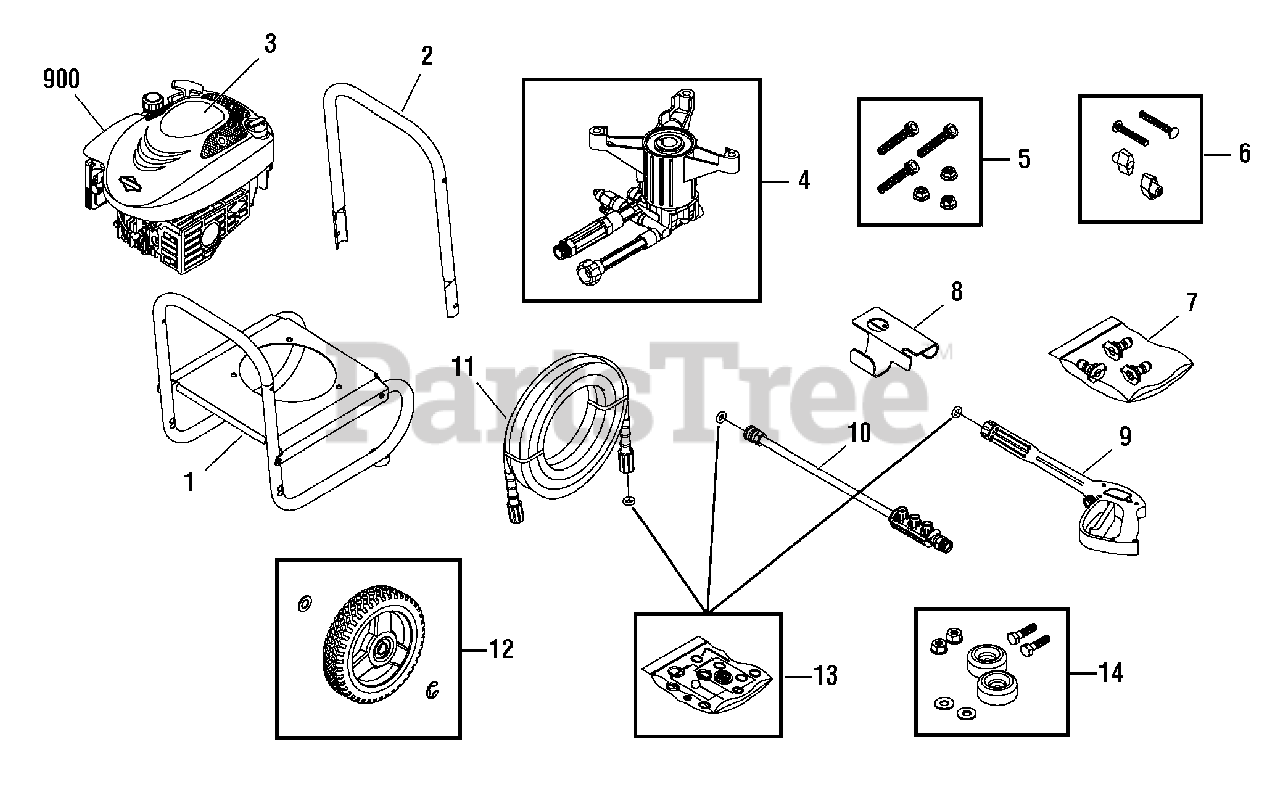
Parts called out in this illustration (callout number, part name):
2	HANDLE
4	PUMP
5	KIT, Hardware, Pump Mounting
6	KIT, Hardware, Handle
7	KIT, QC Nozzles
9	GUN
11	HOSE
13	KIT, O-Ring
14	KIT, Water Inlet
900	* ENGINE
